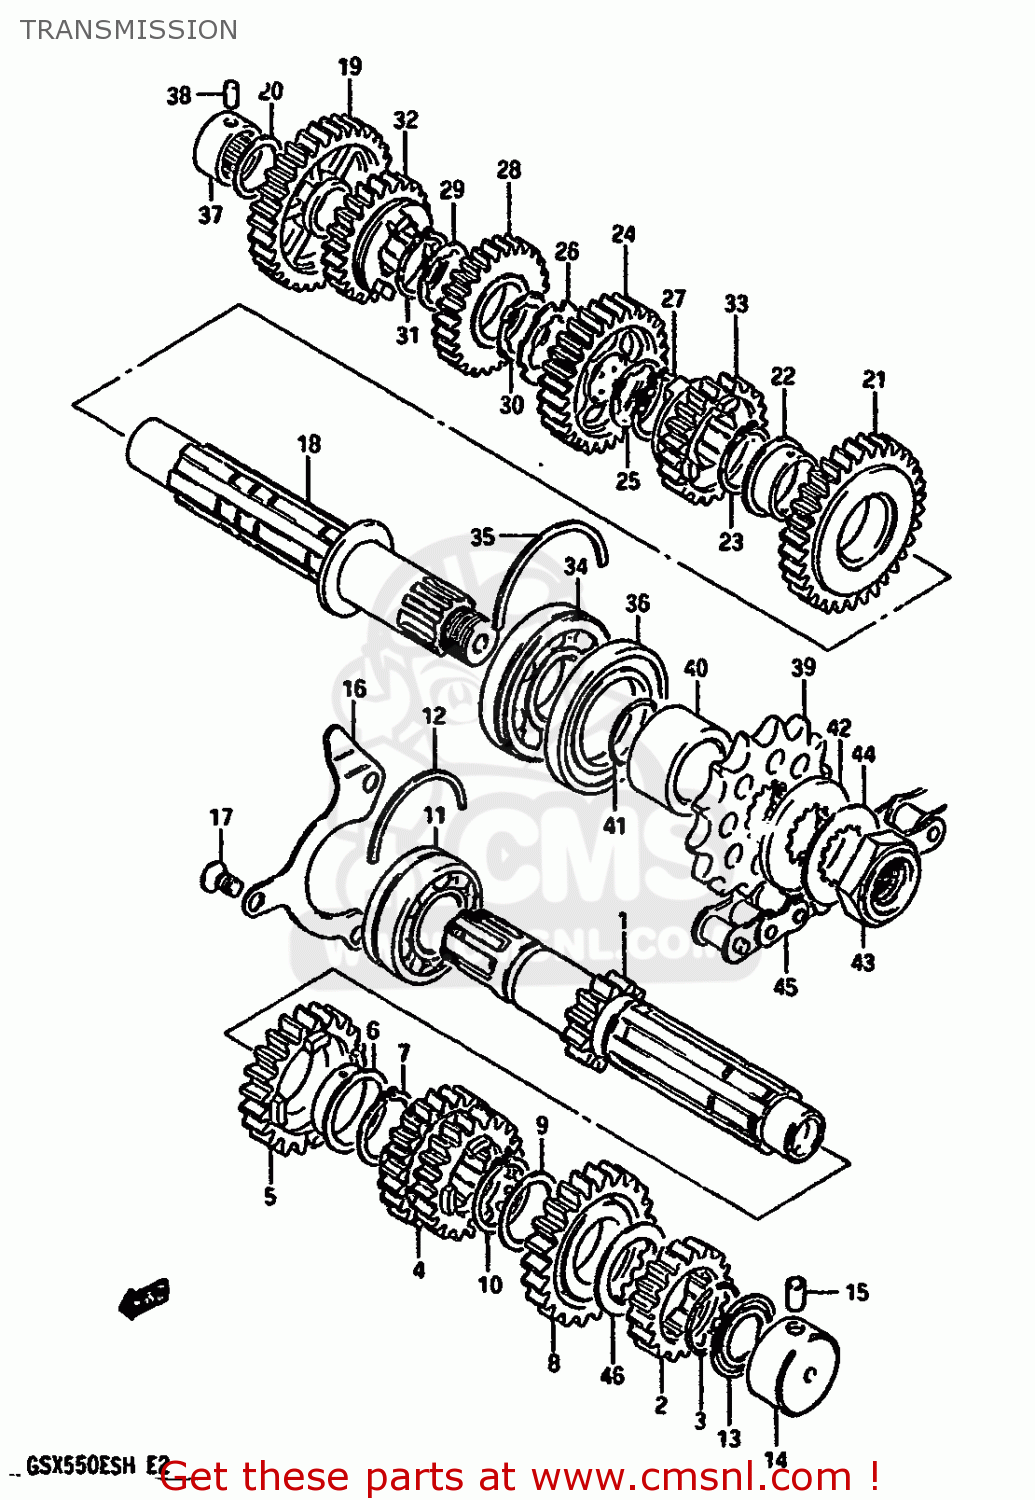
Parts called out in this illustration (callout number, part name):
1	SHAFT,COUNTER
2	GEAR,SECOND DRIVE
3	RING,SNAP
4	GEAR,THIRD/FOURTH DRIVE
5	GEAR,FIFTH DRIVE
6	BUSHING
7	RING,SNAP
8	GEAR,SIXTH DRIVE
9	WASHER,LOCK
10	RING,SNAP
11	BEARING(25X52X19.6)
12	C RING
13	SEAL,OIL(20X31.2X2.7)
14	BEARING(20X34X17.5)
15	PIN
16	PLATE,COUNTERSHAFT BEARING
17	SCREW
18	SHAFT,DRIVE
19	GEAR,FIRST DRIVEN
20	WASHER
21	GEAR,SECOND DRIVEN
22	BUSHING
23	RING,SNAP
24	GEAR,3RD DRIVEN
25	WASHER,LOCK
26	WASHER,LOCK
27	RING,SNAP
28	GEAR,FOURTH DRIVEN
29	WASHER,LOCK
30	WASHER
31	CIRCLIP
32	GEAR,FIFTH DRIVEN
33	GEAR,SIXTH DRIVEN
34	BALL BEARING 25X62X17
35	C-RING
36	SEAL,OIL(33X62X7)
37	BEARING(20X34X20)
38	PIN
39	SPROCKET,ENGINE
40	SPACER (25X33X20.1)
41	O RING(D:1,ID:24.5)
42	SPACER
43	NUT
44	WASHER
45	CHAIN ASSEMBLY,DRIVE
46	SHIM
